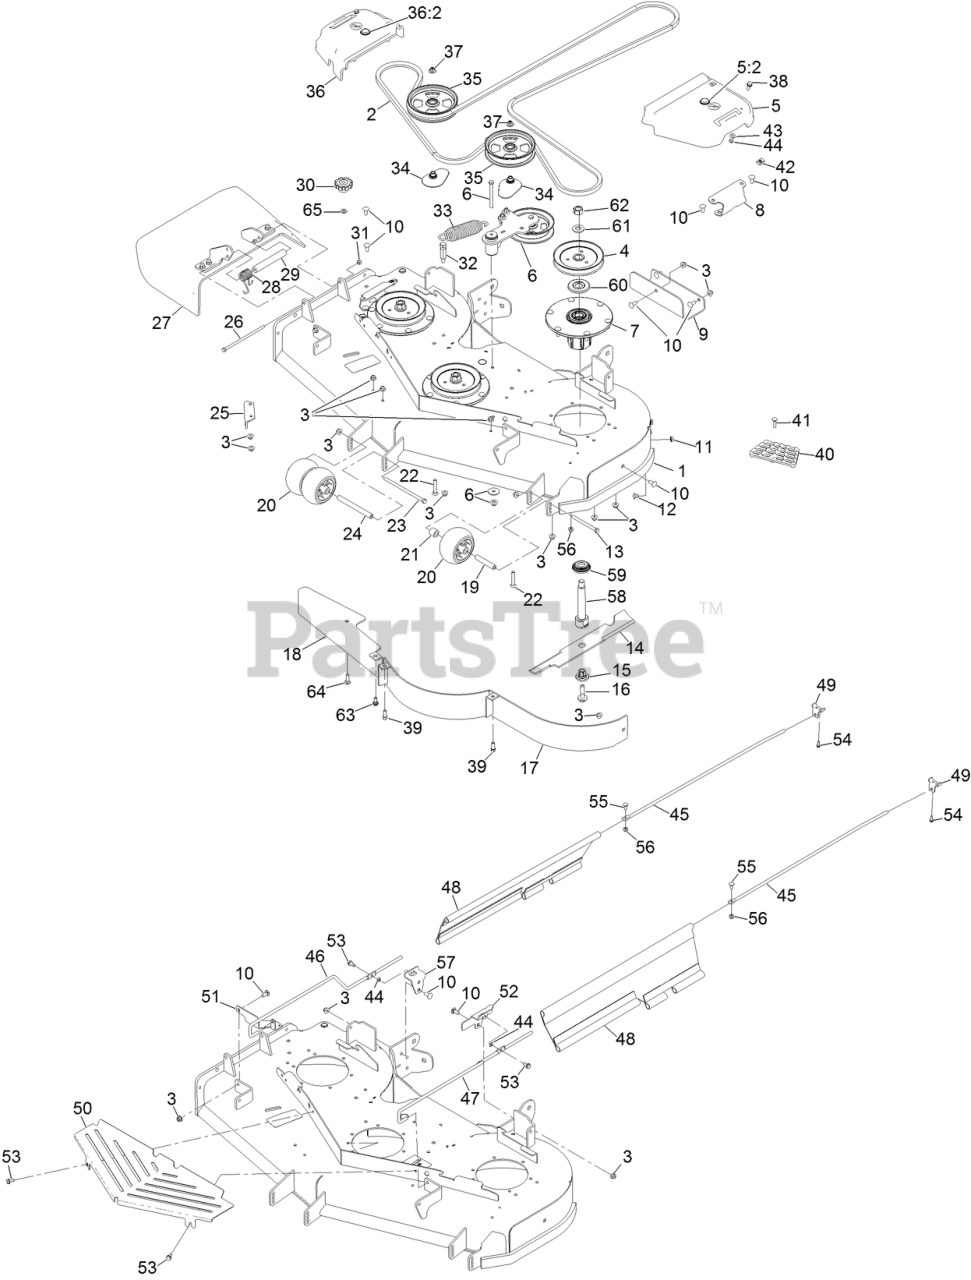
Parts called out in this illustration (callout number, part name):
1	DECK DECAL ASM
2	BELT-V
3	NUT-HF, NI
4	SHEAVE-BLADE DRIVE 6.50
5	LH BELT COVER ASM
5:2	PLUG-PLASTIC
6	IDLER ARM ASM
7	SPINDLE ASM
8	BRACKET-COVER, BELT
9	PLATE-SKID
10	SCREW-CARR
11	NUT-HHF, WHIZ
12	SCREW-CARR
13	SCREW-HH
14	BLADE-FLOW, HIGH
15	BUSHING-HEX
16	SCREW-SEMS
17	BAFFLE ASM
18	PLATE-BAFFLE, FORMED
19	TUBE-SPANNER
20	ROLLER-SCALP, ANTI
21	TUBE-SPACER
22	BOLT-CARR, SHORT NECK
23	SCREW-HH
24	SPACER-WHEEL
25	BAFFLE-DISCHARGE
26	SCREW-HH
27	RUBBER DEFLECTOR ASM
28	SPRING-TORSION
29	SPACER
31	NUT-LOCK, NI
32	ANCHOR-SPRING, TALL
33	SPRING-EXTENSION
34	SPACER-PULLEY
35	PULLEY-IDLER, FLAT
36	RH BELT COVER ASM
36:2	PLUG-PLASTIC
37	NUT-FLANGE, NI
38	SCREW-HHF
40	STEP-DECK
41	SCREW-CARR
42	NUT-U
43	WASHER-THRUST
44	NUT-PUSH
45	ROD-SUPPORT, UPPER
46	ROD-SUPPORT, LOWER (RH)
47	ROD-SUPPORT, LOWER (LH)
48	GUARD-SIDE
49	BRACKET-MOUNTING, UPPER
50	SHIELD-FRONT
51	BRACKET-MOUNTING, FRONT
52	BRACKET-MOUNTING, REAR (LH)
53	SCREW-HWHTF
54	SCREW-HWH
55	SCREW-CARR
56	NUT-HF, NI
57	BRACKET-MOUNTING, REAR (RH)
58	SHAFT-SPINDLE
59	GUARD-BOTTOM
60	GUARD-BEARING, TOP
61	WASHER
62	NUT-HEX
63	BOLT-SHOULDER
64	BOLT-CARR
65	WASHER-HARDENED
